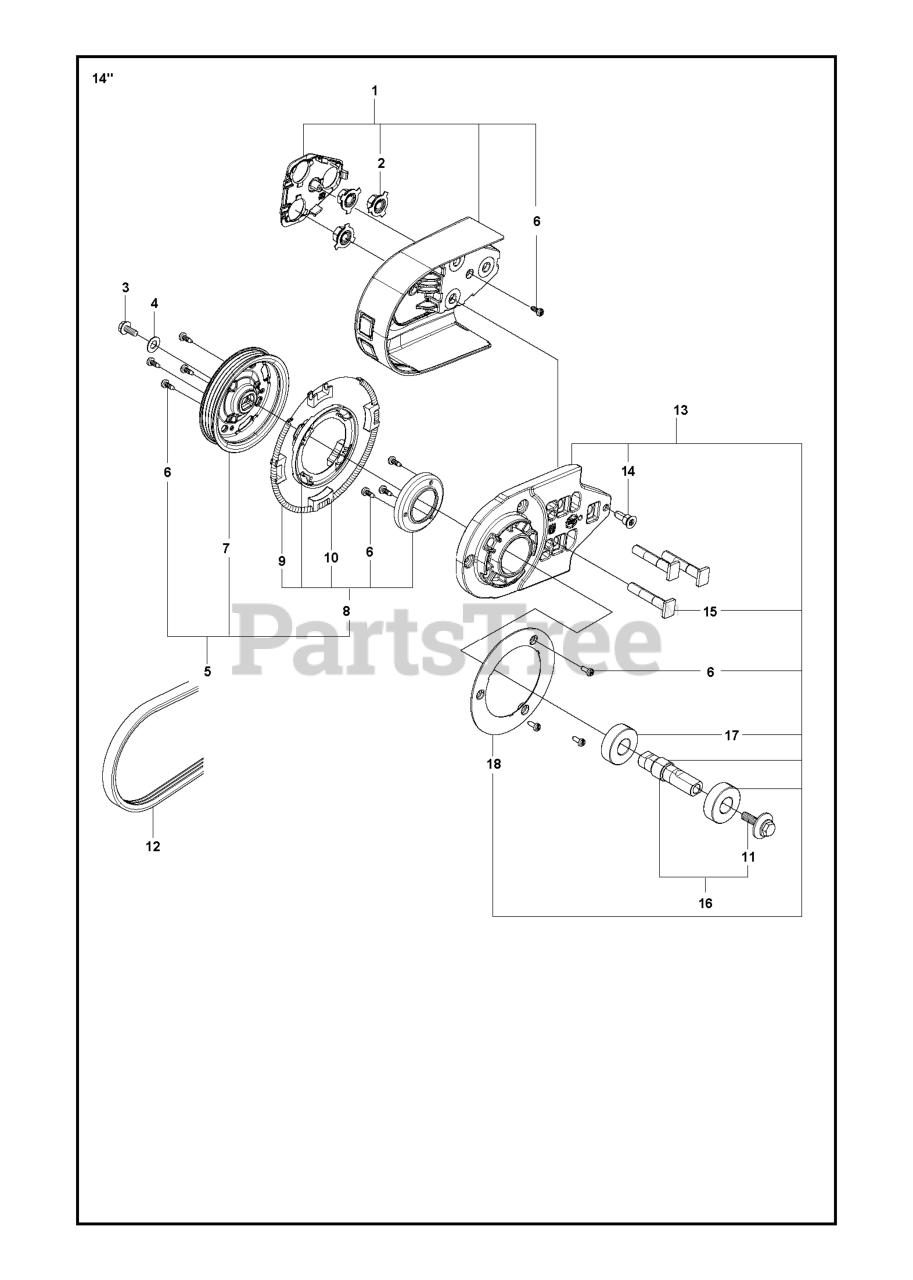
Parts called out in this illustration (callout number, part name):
1	BELT GUARD KIT 14"
2	NUT WASHER ASSY
5	PULLEY ASSY
6	SCREW CITXPANT
7	PULLEY MACHINED PK4
8	CASSETTE FRICTION RETARDER
9	DRAW SPRING
10	BRAKE SHOE
11	SCREW ASSY M10 BLADE
12	BELT PK 870
13	BEARING HOUSING ASSY 14"
14	SCREW WHEEL GUARD ROTATION STO
16	SHAFT KIT M10
17	BALL BEARING
18	SLIP RING HOLDER
